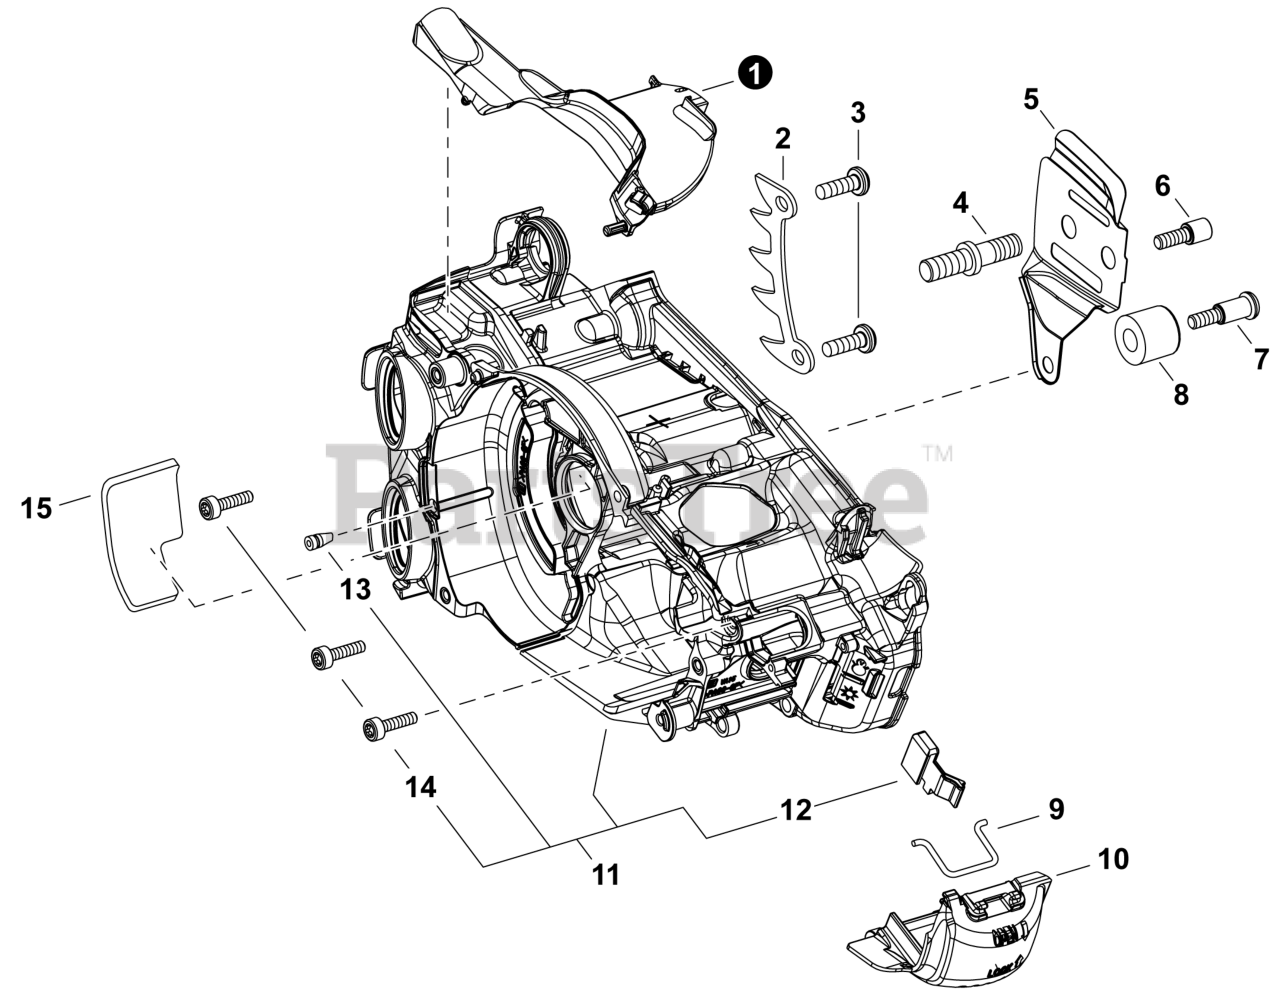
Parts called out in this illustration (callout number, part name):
1	COVER, DUST
2	SPIKE, BUMPER
3	BOLT, TORX 5x12
4	STUD, GUIDE BAR
5	PLATE, GUIDE - INNER
7	BOLT 5x12
8	CATCHER, CHAIN
9	LATCH, COVER
10	COVER, SPARK PLUG
11	ENGINE COVER ASSY
12	SHUTTER, AIR
13	VENT ASSY
14	BOLT, TORX 4x16
15	SHIELD, HEAT
